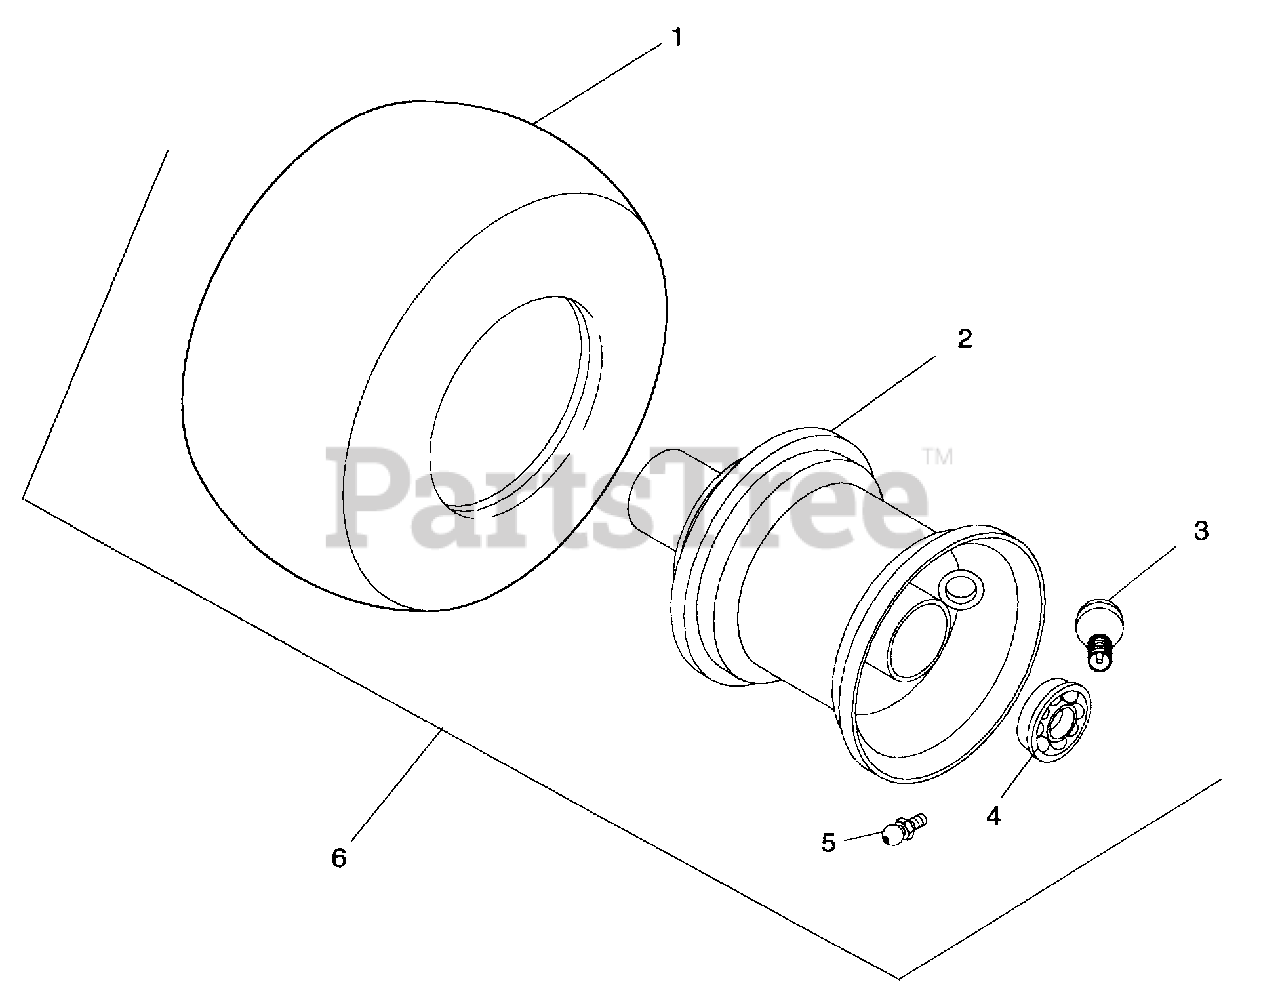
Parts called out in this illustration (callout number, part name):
1	Tire, 13 x 6.00-6
2	Rim-Assembly 4.5 x 3.75
3	Valve Stem Assembly
4	Radial Bearing
5	Fitting-Lube .25-28 x .256
6	Assembly, Wheel, 13 x 6.00-6, Pro
